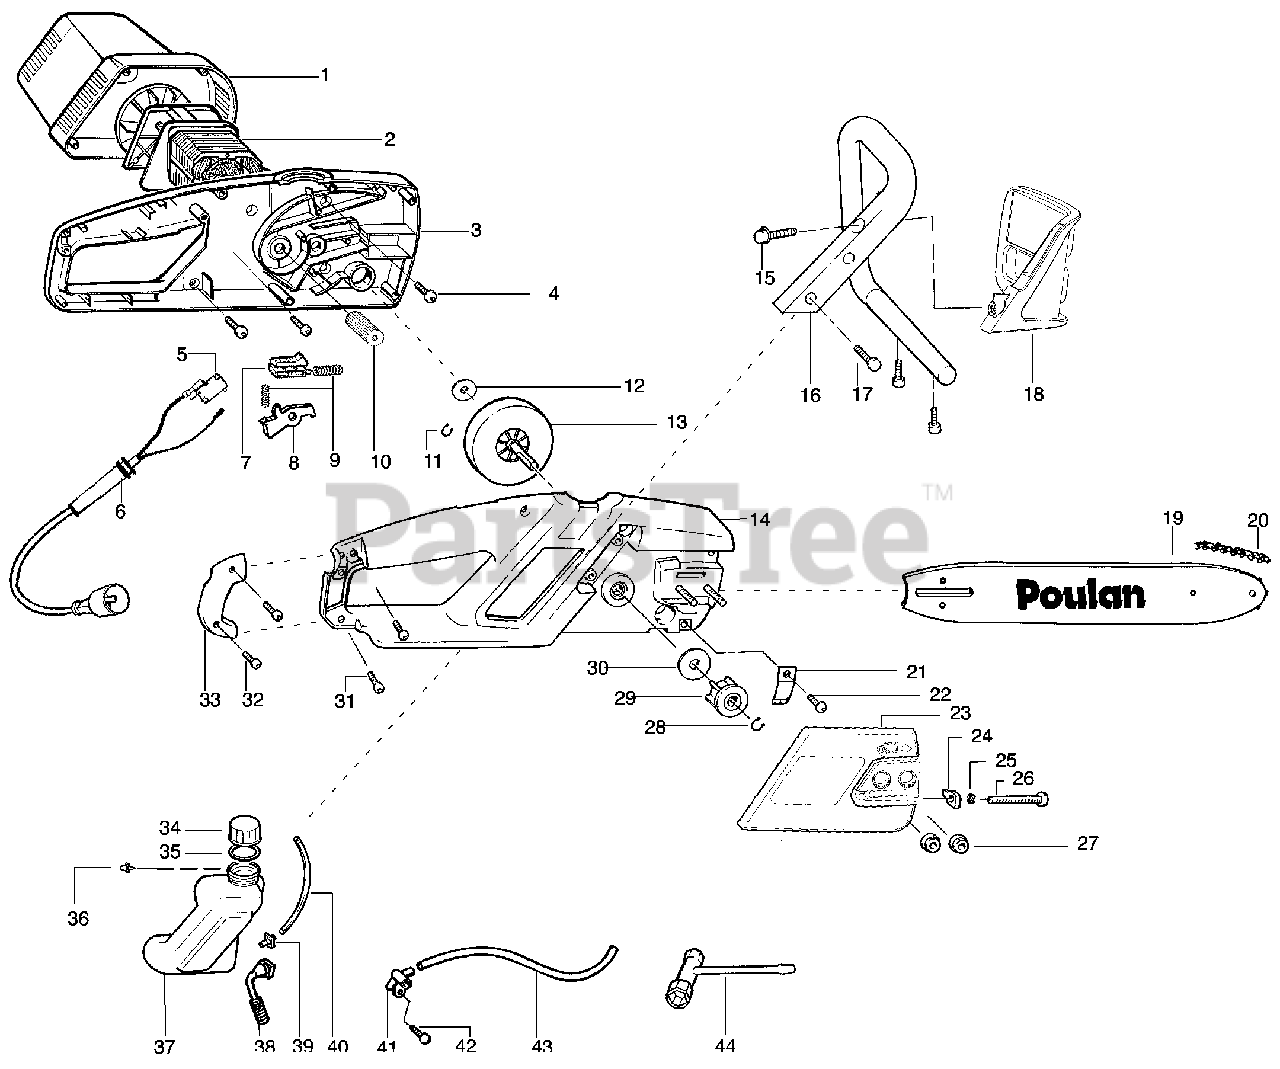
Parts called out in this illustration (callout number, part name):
1	Motor Cover
2	Motor Outline
3	Assy-Housing
5	Switch-Momentary
6	Assy-Harness
7	Lockout Button
9	Spring-Trigger
11	Ring-Retainer
12	Washer-Thrust
13	Gear Drive
14	Housing Cover
16	Front Handle
18	Handguard
20	Chain-16"
21	Chain Catcher
23	Bar Clamp
24	Pin-Bar Adjust
25	Retainer-Bar Ajdust
26	Screw-Bar Adjust
27	Nut-Bar Mounting
28	Ring-Retainer
29	Sprocket (3/8 Pitch)
30	Washer-Sprocket
33	Cover Access
34	Oil Cap
35	O-Ring
36	Check Valve
37	Oil Tank Ass'y.
38	Oil Pickup Ass'y.
39	Oil Pickup Fitting
40	Inlet Line
41	Oil Pump Ass'y.
43	Outlet Line
44	Bar Wrench
